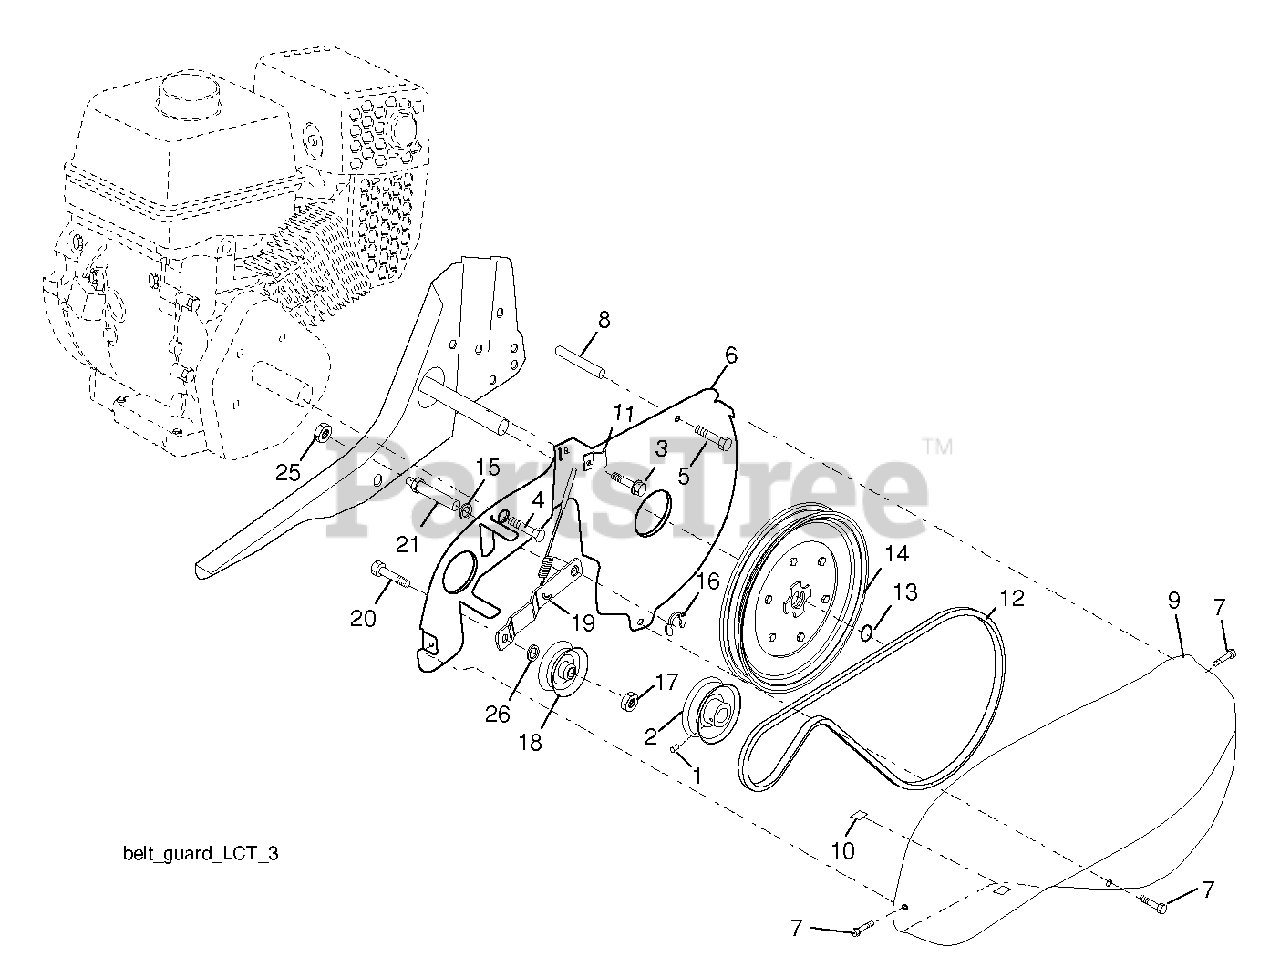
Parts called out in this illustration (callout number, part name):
1	SET SCREW
2	ENGINE PULLEY
3	SCREW.HXTAP.10-24
5	BOLT, THD ROLLER 1/4-20 X 2-1/
6	SHIELD.INNER.FRT.BLACK
7	SCREW.HEX.WSH.SLT.#10-24X.50
8	SPACER.SPLIT
10	PAD IDLER TI
11	CLIP.PLATED
12	V BELT STD
13	RETAINING RING LT
14	SHEAVE.TRANS
15	WASHER FLUT
16	KLIP RING TI
17	NUT.LOCK.5/16-18
18	PULLEY.W/SPACER.2.25
19	ARM.ASM.IDLER.PNT
20	HEX BOLT
21	SHAFT.IDLER.TILLER
25	JAM NUT TI
26	WASHER.20X8.5
